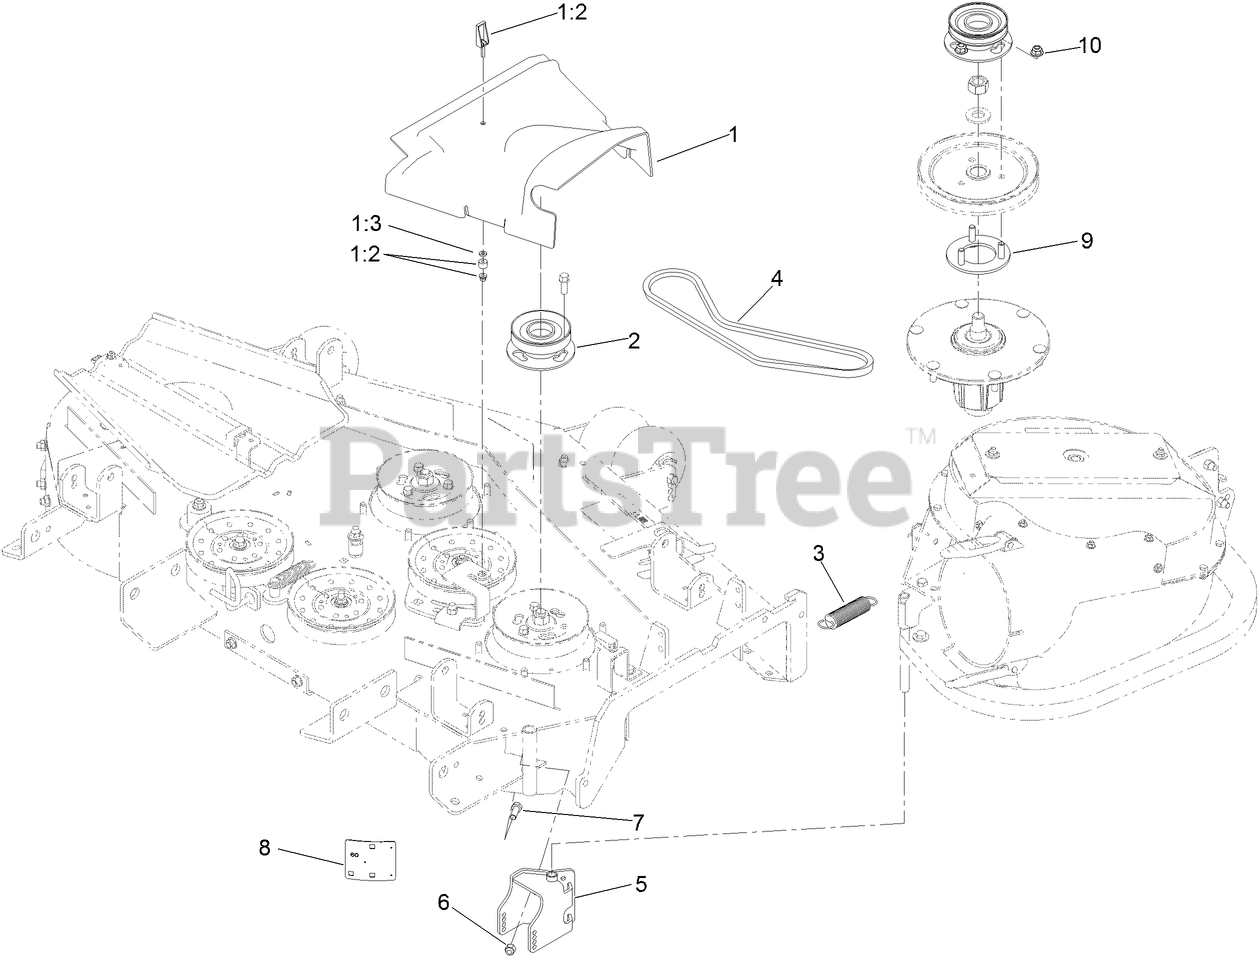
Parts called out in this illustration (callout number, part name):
1	BELT COVER ASM
1:2	LATCH-SWELL
1:3	WASHER
3	SPRING-EXTENSION
4	BELT-V
5	HINGE-BLOWER
6	NUT-LOCK, NI
7	SCREW-HH
8	TEMPLATE
9	PULLEY MOUNT ASM
10	NUT-HF, NI
